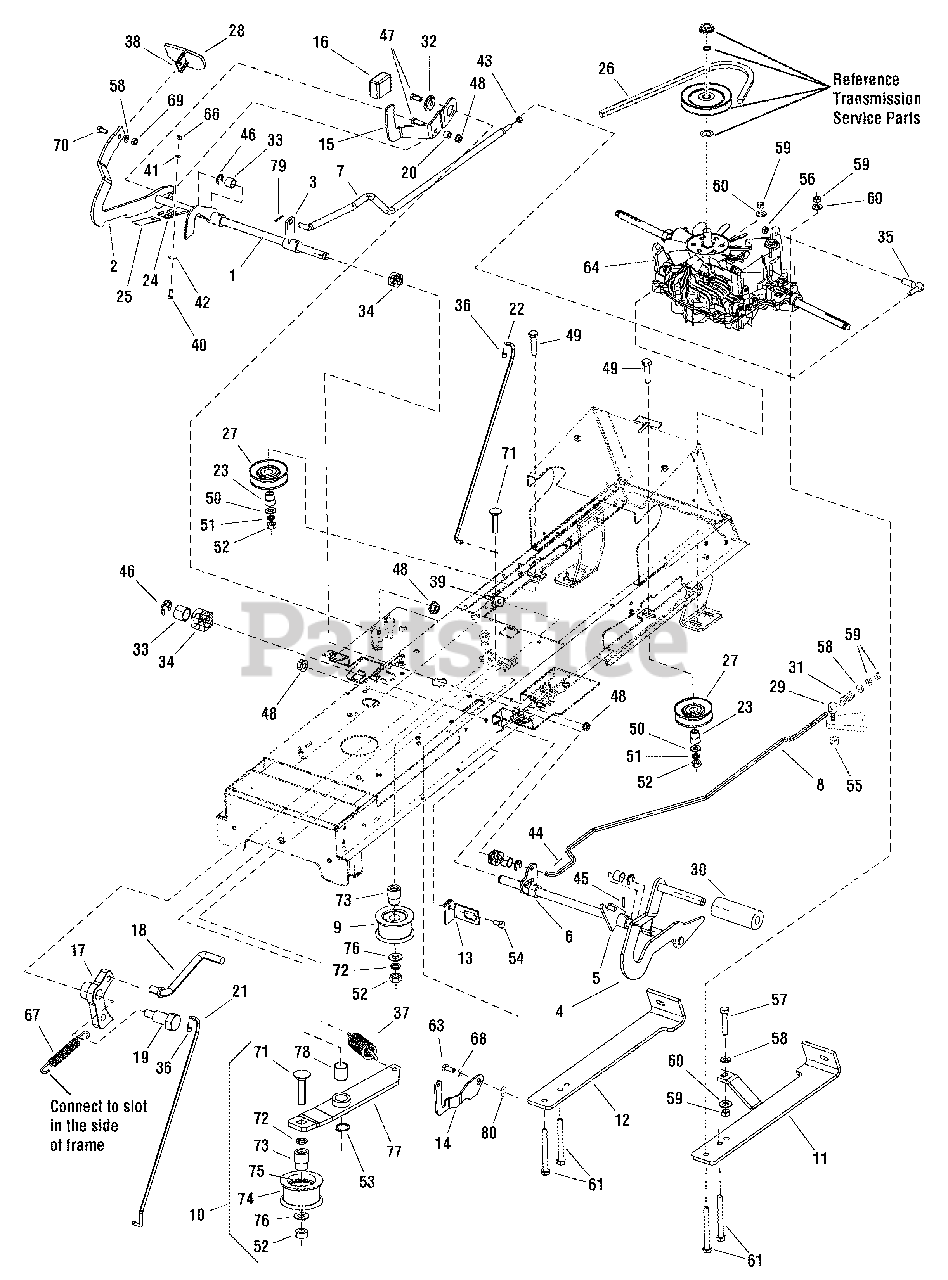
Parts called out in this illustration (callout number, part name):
1	PEDAL, Forward
2	RATCHET
4	PEDAL, Brake
5	LEVER, Parking Brake
6	LEVER, Brake
7	ROD, Traveling
8	ROD, Brake
9	PULLEY, Tensioning
10	PULLEY, Idler
11	HOLDER, Left
12	HOLDER, Right
13	SUPPORT, Switch
14	LATCH, Brake Lock
15	PEDAL, Reverse
16	PAD, Foot Pedal
17	LATCH, Cruise
18	ROD, Cruise 5/16 Dia. x 2.83"
19	BOLT, Shoulder, 5/16-18 x 1-5/8
20	SPACER, Foot Pedal
21	ROD, Cruise Latch, Upper
22	ROD, 15.95 lg
23	BUSHING, 0-9421-418
24	WASHER, Lock
25	SPRING, Flat 0-9740-221
26	V-BELT, Li, BBT, 13 x 2580
27	PULLEY, Compensa C-00237/1
28	PEDAL, Forward Rubber
29	BOLT, 0-9016-447
30	PEDAL, Brake Pad
31	SPRING, TLZ 250.150.0530 Yellow
32	SPACER, Pivot
33	DISTANCE, Pedal 0-9521-288
34	BUSHING, 0-9462-202
35	BALL JOINT, CS 13 DIN 71802 M8, Silver
36	CLIP, Linkage .250 dia
37	SPRING, TZ 2x14x62, Yellow
38	PEDAL, Forward, Top
39	BOLT, Eye M6x80 BN1006
40	BOLT, M6 x 16
41	WASHER, 6.4
42	WASHER, 6
43	NUT, M8
44	SPINDLE, 2 x 20
45	PIN, Flex. 5 x 25
46	LOCK RING, 12
47	BOLT, Carriage, 5/16-18 x 1-1/4
48	NUT, Hex Flange, 5/16-18
49	BOLT, M10 x 40
50	WASHER, 10.5
51	WASHER, 10.0
52	NUT, M10
53	LOCK RING, 16
54	SCREW, Tap, 5/16-18 x 5/8
55	NUT, M10
56	NUT, M8 DIN 6923 8 Yellow, Tooth
57	BOLT, M8 x 45
58	WASHER, 8.4
59	NUT, M8
60	WASHER, 8
61	BOLT, M8 x 75
63	BOLT, Shoulder 5/16-18 x 1-3/16
64	TRANSMISSION, Tuff Torq, K-46BL
64	TRANSMISSION, Tuff Torq, K-46CW
66	NUT, M6
67	SPRING
68	WASHER, 14x26/0.2
69	NUT, M8
70	BOLT, M8 x 20
71	SCREW, M10 x 45
72	LOCK RING, 40
73	BUSHING, Pulley, Tension
75	BALL BEARING, Pulley, 62032RS
76	WASHER, 11
77	ARM, Pulley, Tension
78	BEARING, Slide
79	SPINDLE, 3.2 x 25
80	WASHER, 16 x 22 x 1
